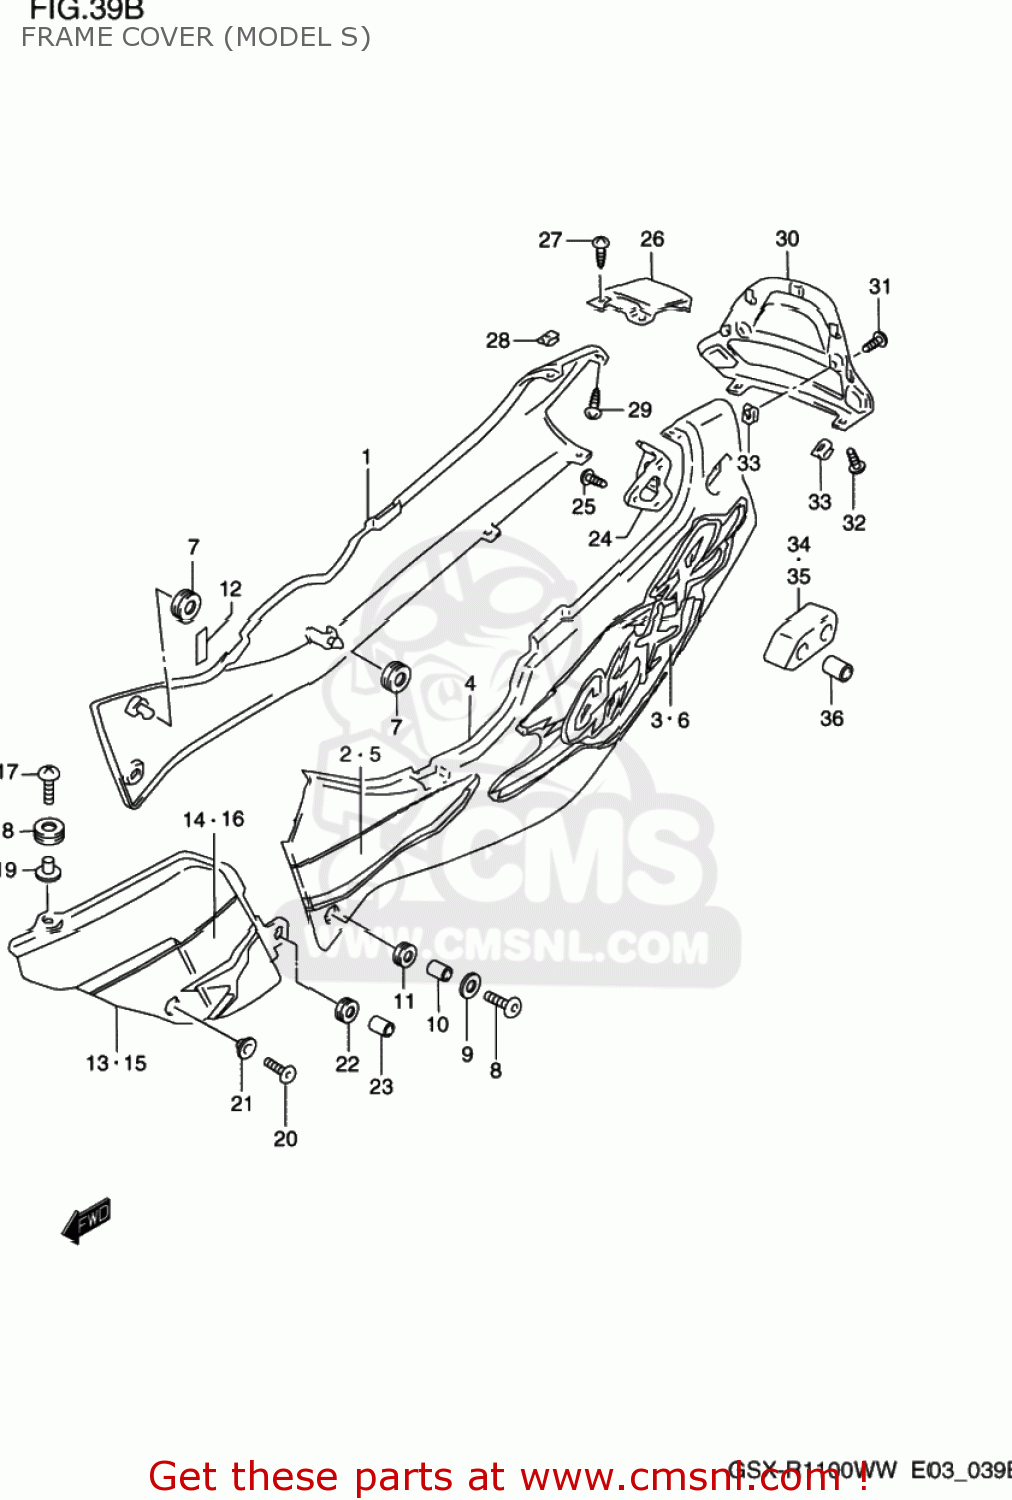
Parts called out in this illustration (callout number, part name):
1	COVER ASSY,FRAME,R(WHITE)
2	TAPE,FRAME COVER,RIGHT
3	EMBLEM,FRAME COVER,R
4	COVER ASSEMBLY,FRAME,LEFT
5	TAPE,FRAME COVER,L
6	EMBLEM,FRAME COVER,LEFT
7	CUSHION
8	SCREW(6X30)
9	WASHER
10	SPACER (6.1X9X9)
11	CUSHION
12	CUSHION
13	COVER ASSY,FRAME BODY,R
14	TAPE,FRAME COVER BODY,R
15	COVER ASSEMBLY,FRAME BODY
16	TAPE,FRAME COVER BODY
17	SCREW(6X25)
18	CUSHION
19	WASHER
20	SCREW(5X14)
21	WASHER
22	CUSHION
23	SPACER (6.1X9X9)
24	BRACKET,RR COMBINATION LAMP,L
25	SCREW
26	COVER ASSY,FRAME CTR
27	SCREW 5X12
28	NUT
29	SCREW
30	COVER,FRAME RR
31	SCREW(5X12)
32	SCREW 5X12
33	NUT
34	CUSHION,PILLION RIDER HANDLE,R
35	CUSHION,PILLION RIDER HANDLE,L
36	SPACER (8.5X16X37)
